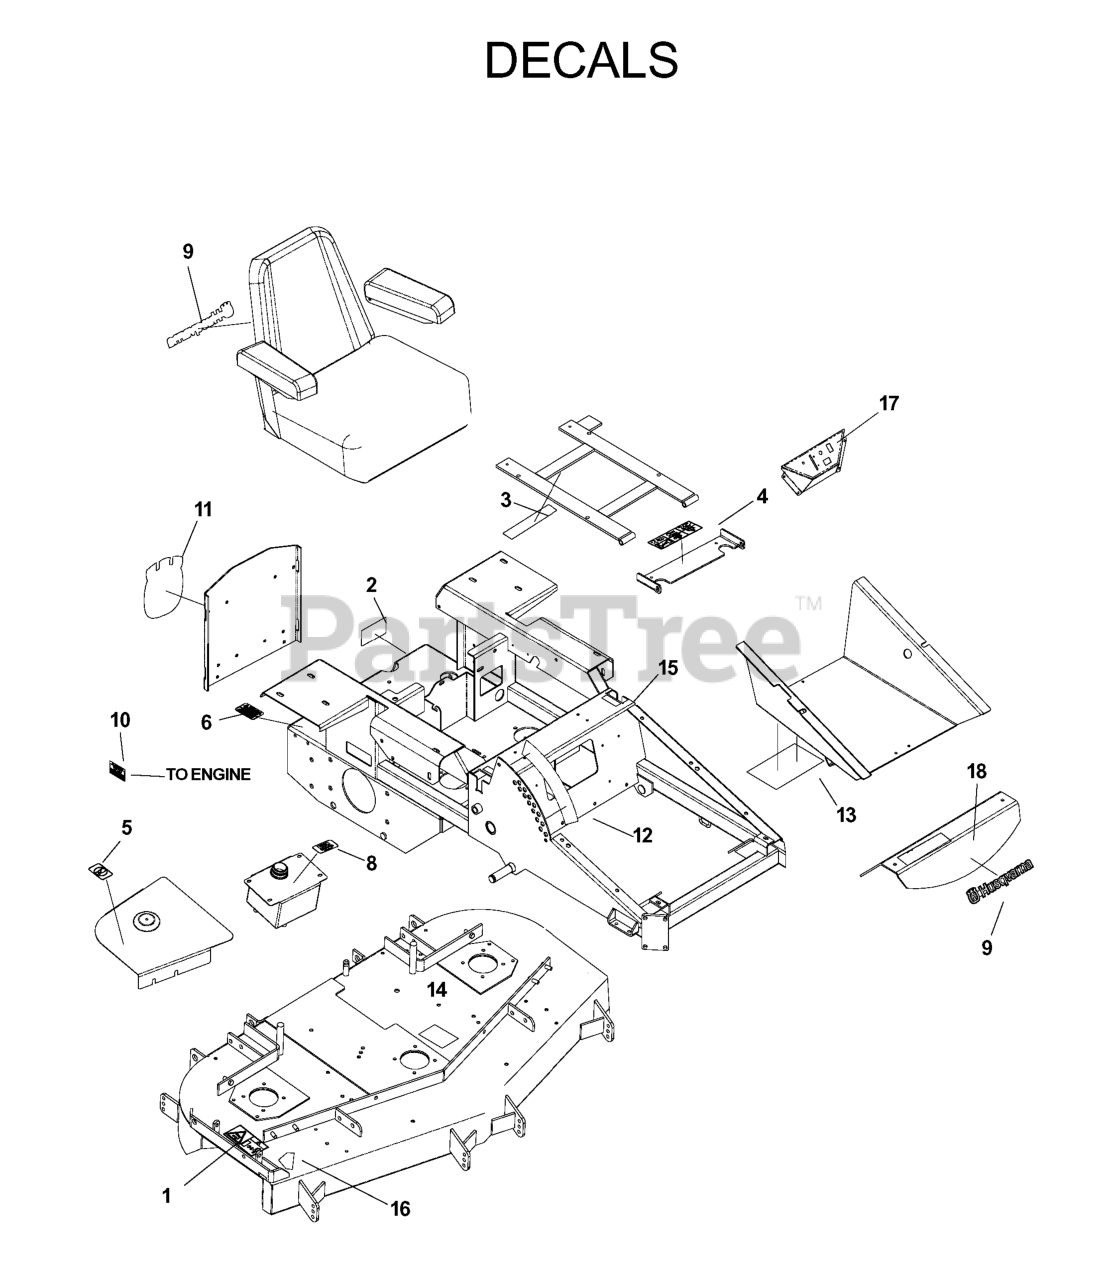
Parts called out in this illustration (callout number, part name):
1	DECAL, EURO SEVERING
2	DECAL, BELT DRIVE
3	EURO DECAL-BATTERY WARNIN6
4	DECAL, EURO WARNING
5	DECAL, NO STEP
6	DECAL, PROP. 65
8	DECAL, MOBIL 1
9	DECAL, HUSQVARNA LOGO 9.25"
10	DECAL, EXHAUST
11	DECAL, LGE CROWN 7X6"
13	SERVICE DECAL
14	BELT ROUTING DECAL
15	DECAL, MOTION CONTROL
16	DECAL, CPSC
17	DECAL - CE CONSOLE
18	DECAL - IZIZ4218
539102670	DECAL, FUEL VALVE
539107745	DECAL - IZ4821
